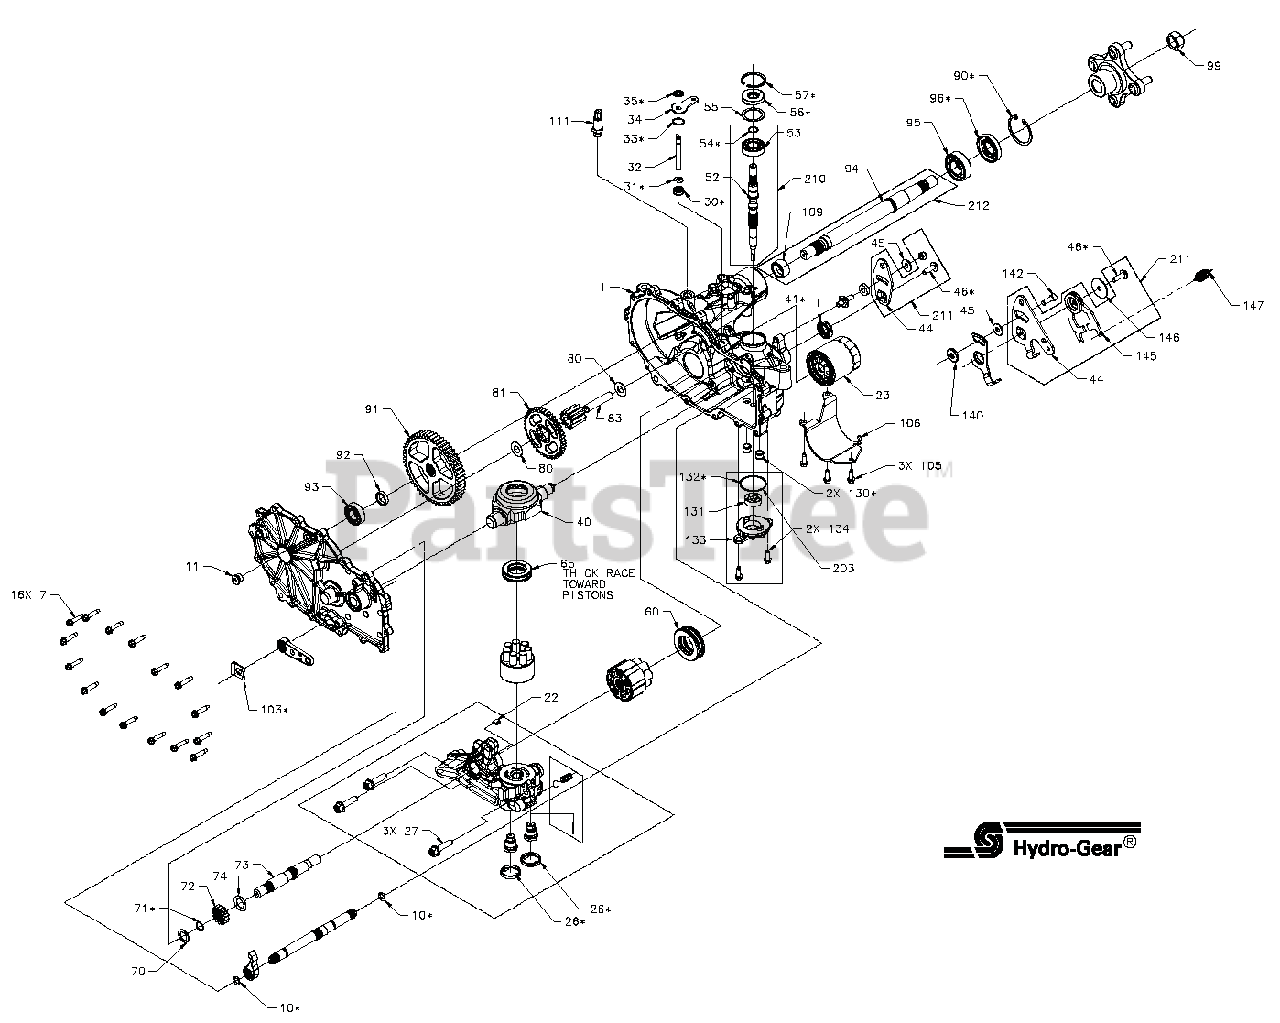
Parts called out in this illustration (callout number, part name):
1	Kit, Main Housing RH
7	HFHCS 1/4-20 X 1.25"
11	PLUG, STEEL (WITH SEAL)
22	PLATE, BYPASS
23	Filter, Oil
30	SEAL, LIP .375X.75X.25
31	RING. RETAINING
32	Rod, Bypass
33	RING, RET .750
34	Arm, Bypass
35	RING, RTNG .
40	TRUNNION, SWASHPLATE
45	WASHER
46	TWHCS 5/16-24 X 1.00
52	Shaft, Input
53	BRG, BALL 17X40X12
54	Ring, Ret Wire .561 ID
55	WASHER 1.23X1.56X.04
56	SEAL, LIP 17X40X7
57	RING, RET 1.56 INT
60	Bearing, Thrust
65	BEARING. THRUST 30 X 52 X 13
70	WASHER .63X1.0X.05
71	RING, RET 62 EXT
72	Gear, 13T, Steel
73	Shaft, Motor
74	WASHER .71 X 1.16 X .04
80	WASHER .5X1.0X.032
83	JACK SHAFT (PIN)
90	RING, RETAINING
95	BEARING, BALL 25.4 X 52 X 15
96	SEAL, LIP
99	NUT, HEX, LOCK 3/4-16
103	Clip, Retaining
105	HFHCS 1/4-20X.75
106	Guard, Filter, RH
111	Fitting, Str 9/16-18 SAE .5 Barb
130	Tube, Connecting
131	GEROTOR
133	Cover, Charge Pump
134	HFHCS 1/4-20X.75
142	SHCS 5/16-24X1 PATCH
146	WASHER
147	Spring, Extension Rtn - 34 lbs
200	Kit, Seal ( * - parts included in this kit)
NS	SEALANT TUBE 10.1OZ.
NS	20W50 Oil
